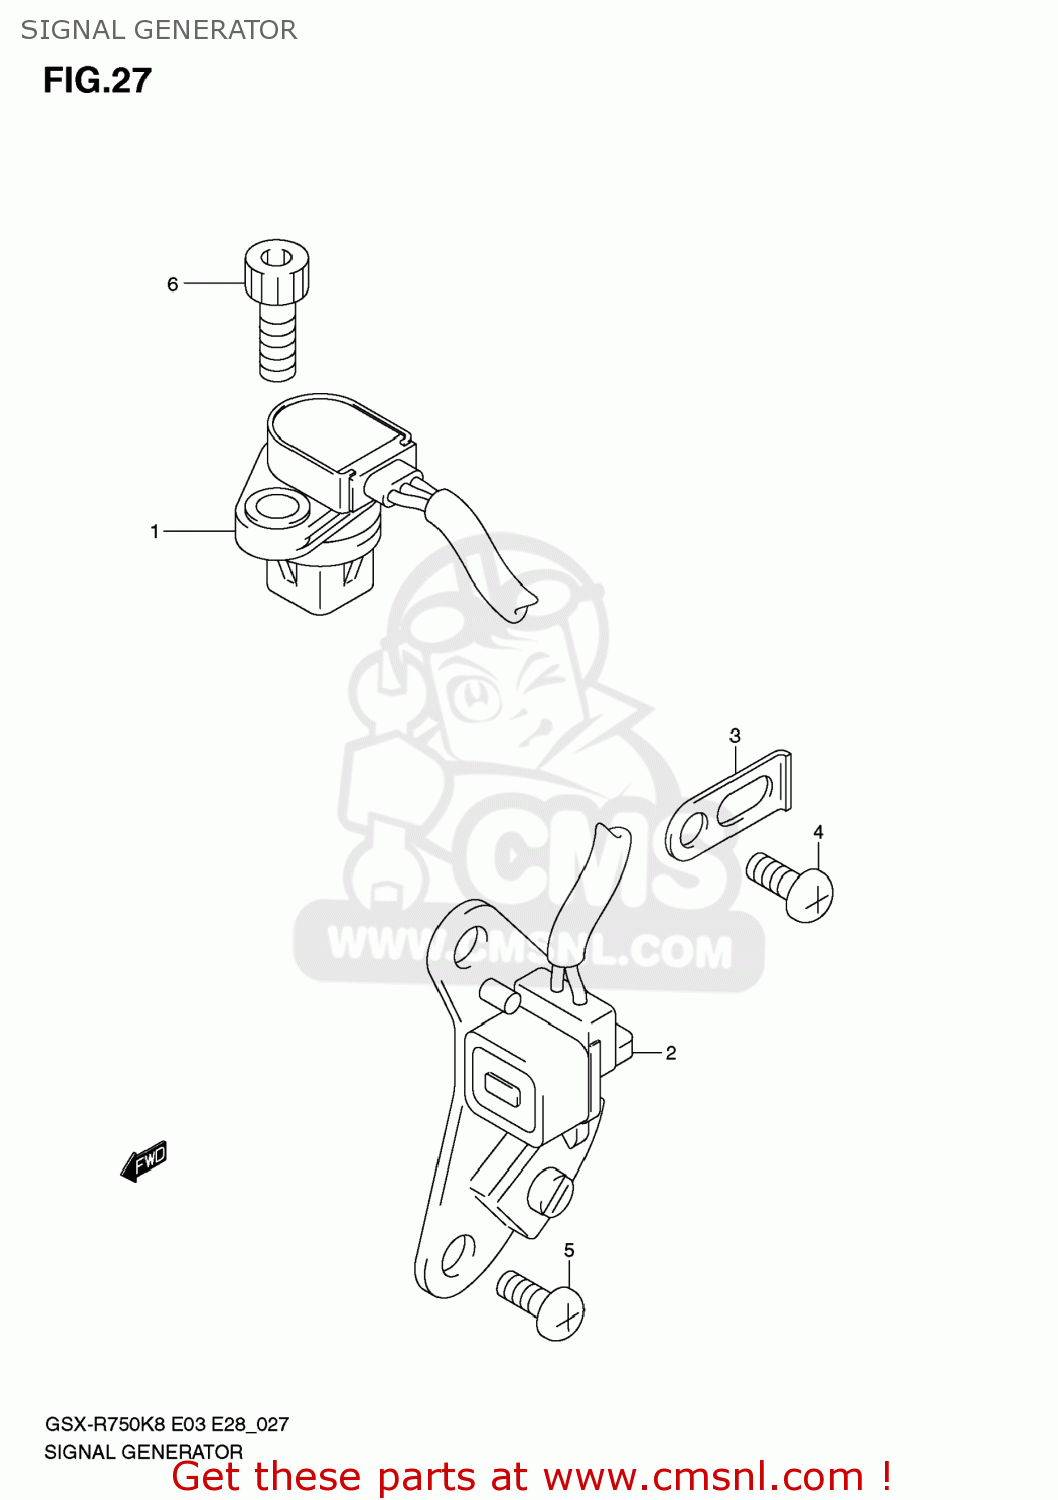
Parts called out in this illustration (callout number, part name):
1	SENSOR ASSY,CAM POSITION
2	STARTER,SIGNAL GENERATOR
3	CLAMP,SIGNAL GENERATORERATOR
4	SCREW
5	SCREW
6	BOLT
